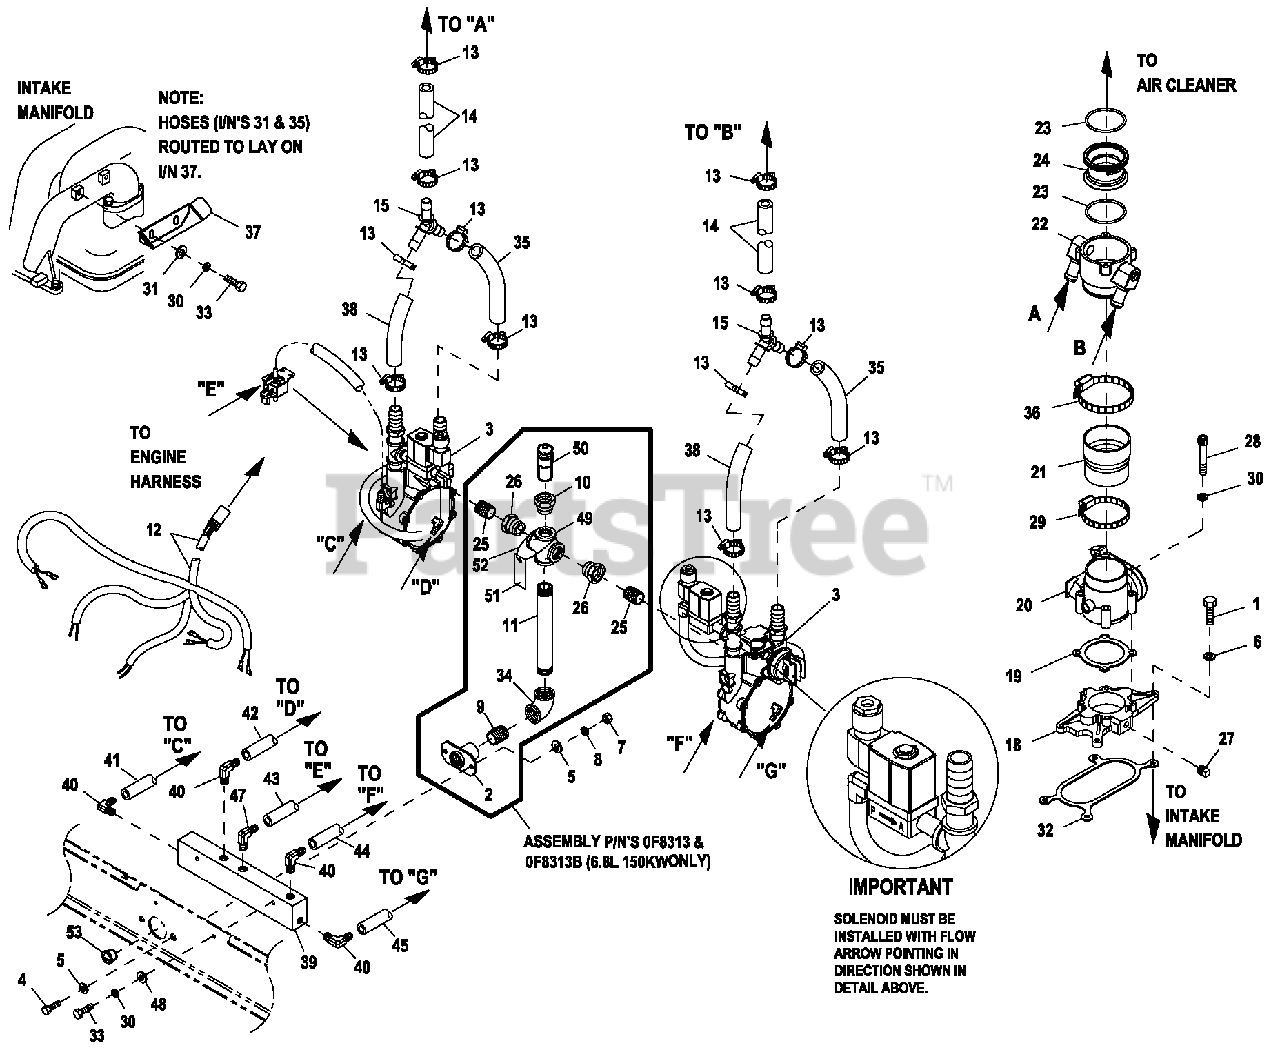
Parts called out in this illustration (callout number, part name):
1	SCREW HHC 5/16-18 X 1-1/4 G5
2	SUPPORT NAT GAS SOLENOID
3	REG 6.8L CPL 130 KW N/G EMISS
4	SCREW HHC M12-1.75X30 C8.8
5	WASHER FLAT 1/2 ZINC
6	WASHER LOCK M8-5/16
7	NUT HEX M12-1.75 G8 YEL CHR
8	WASHER LOCK 1/2
9	NIPPLE CLOSE 1.25 NPT X 1.625
10	BSHG RDCR HEX 1-1/4 X 1/4FNPT
11	NIPPLE PIPE 1-1/4 NPT X 7 (130 KW ONLY)
12	HARNESS FUEL JUMPER DUAL REG
13	CLAMP HOSE #8 .53-1.00
14	HOSE 3/4 ID SAE-30R2 (42" LG)
15	Y CONNECTOR 500 SERIES BARBS
18	ADAPTOR THROTTLE BODY
19	GAS KET GOVERNOR ACTUATOR
20	ACTUATOR BOSCH 60 GOVERNOR
21	REDUCER 3.0" TO 2.75" TURBO
22	MIXER 40/60MM ACTUATOR ASSY
23	O-RING 2-3/4 X 3/32 X 2-15/16
24	VENTURI THROTTLE 44MM (130KW)
25	NIPPLE CLOSE 3/4 X 1.375
26	BSHG RDCR HEX 1-1/4-3/4
27	PLUG STD PIPE 1/4 STEEL SQ HD
28	SCREW SHC M6-1.0 X 50 C8.8
29	CLAMP HOSE #44 2.31-3.25
30	WASHER LOC K M6-1/4
31	WASHER FLAT M6
32	GAS KET ADAPTER THROT BODY
33	SCREW HHC M6-1.0 X 20 G8.8
34	ELBOW 90D 1-1/4NPT
35	HOSE 3/4 ID SAE-30R2 (12" LG)
36	CLAMP HOSE #52 2.81-3.75
37	BRACKET, HOSE RISER
38	HOSE 3/4 ID SAE-30R2 (9.5" LG)
39	MANIFOLD, EMISSIONS VACUUM
40	BARBED EL 90 3/16X1/8
41	HOSE VACUUM 5/32 (5"LG)
42	HOSE VACUUM 5/32 (7"LG)
43	HOSE VACUUM 5/32 (18"LG)
44	HOSE VACUUM 5/32 (6"LG)
45	HOSE VACUUM 5/32 (8"LG)
47	BARBED EL W/VENT (.052")
48	WASHER FLAT 1/4-M6 ZINC
49	PIPE CROSS 1-1/4" NPT
50	PLUG, PRESSURE GAUGE, 1/4" NPT
51	HANG TAG FUEL PRESS TEST POINT
52	TIE WRAP UL 5.6 X .10 BLACK
53	PLUG PLASTIC 1.25" TAPERED CAP
